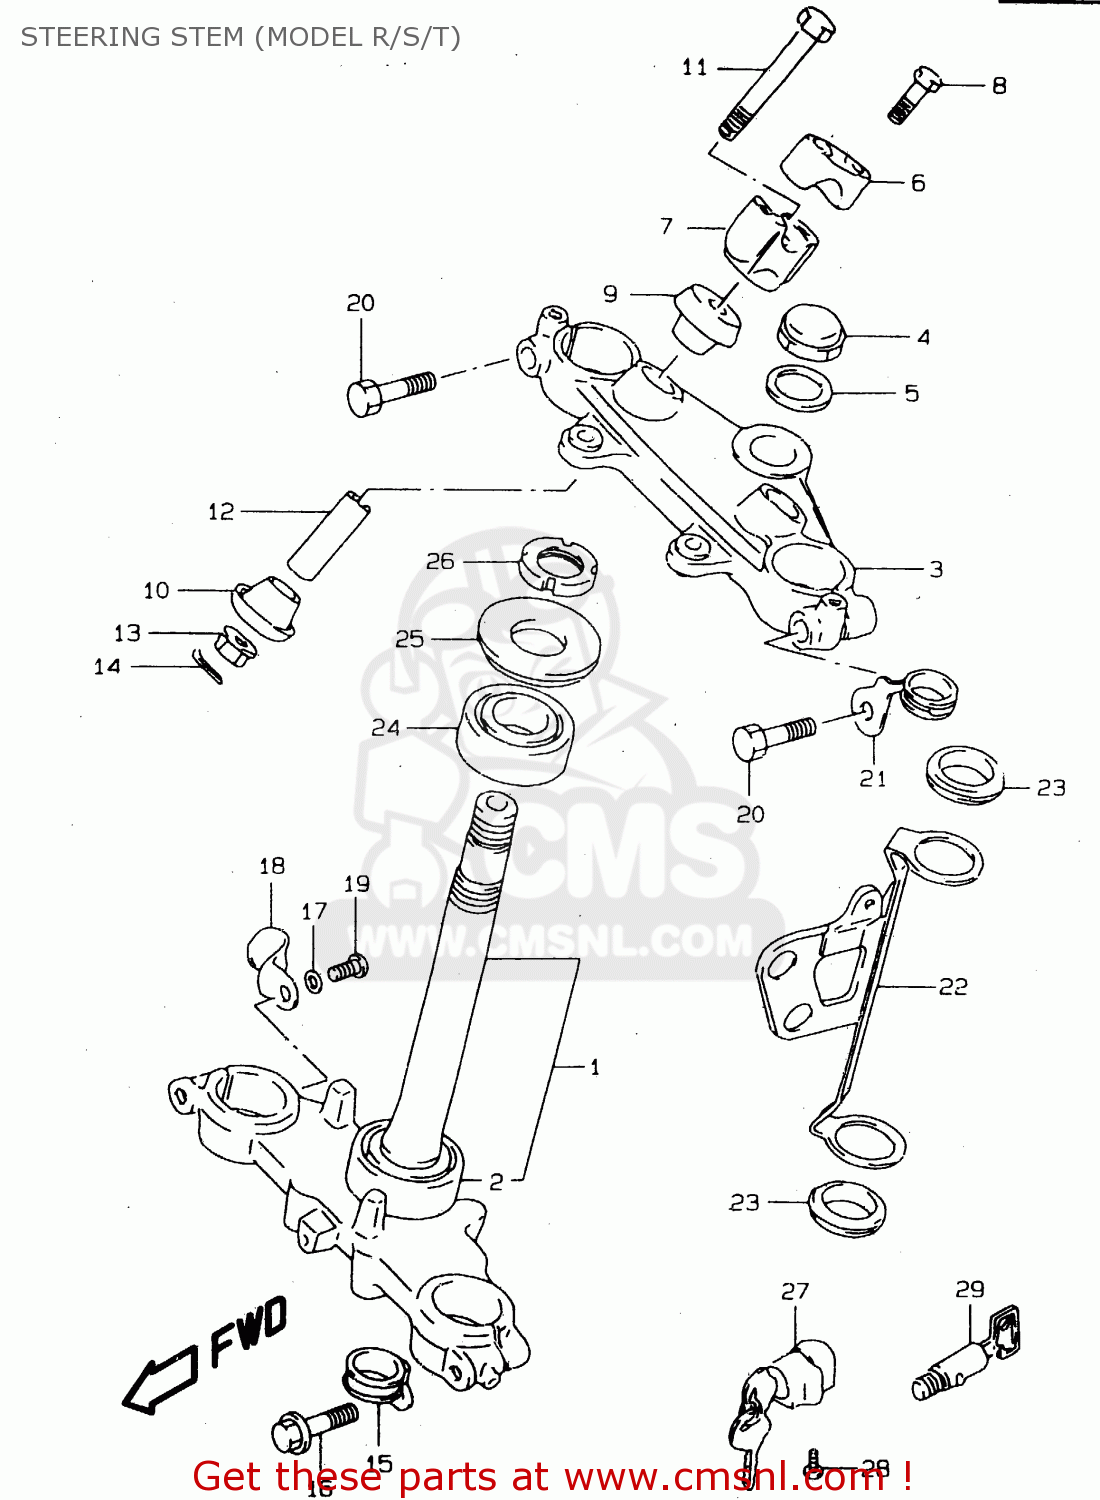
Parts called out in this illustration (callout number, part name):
1	STEM,STEERING
2	BEARING(30X55X17)
3	HEAD,STEERING STEM
4	NUT,CAP
5	WASHER
6	HOLDER,HANDLE UPR
7	HOLDER,HANDLEBAR LWR
8	BOLT
9	RUBBER,HANDLE HOLDER
10	RUBBER,LWR
11	BOLT,LWR HOLDER
12	SPACER
13	NUT
14	COTTER PIN
15	CLIP,LOWER
16	BOLT
17	WASHER,LOCK
18	CLIP
19	SCREW
20	BOLT
21	CLIP
22	BRACKET,HEADLAMP,R
23	CUSHION,HEADLAMP HSG BRACKET
24	BEARING(25X47X15)
25	SEAL,STEERING UPR DUST
26	NUT,STEERING
27	LOCK SET,STEERING
28	SCREW
29	LOCK ASSY,STEERING(NEIMAN)
